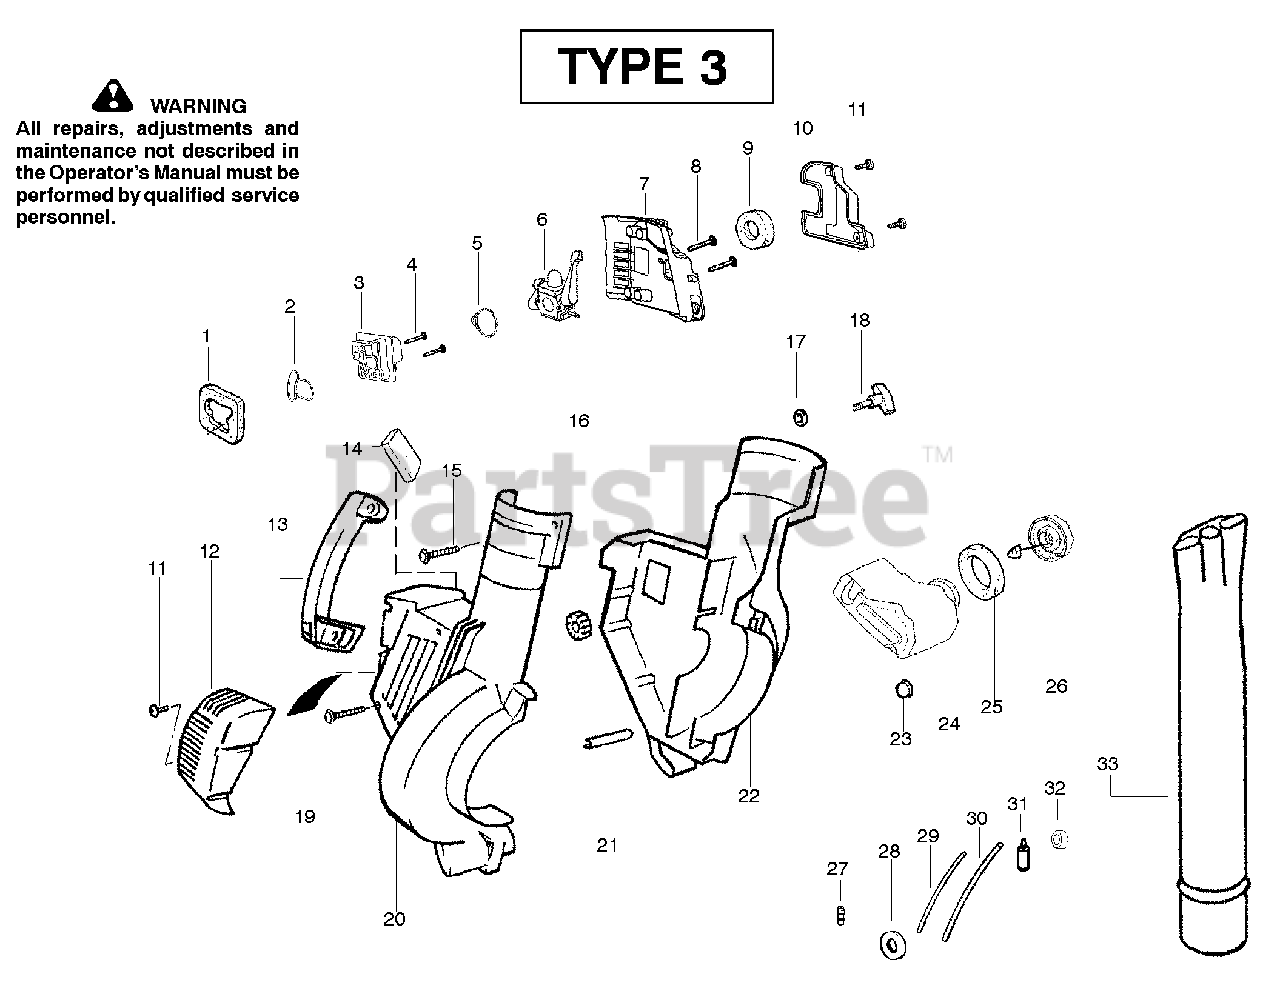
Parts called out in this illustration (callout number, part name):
1	Air Dam (kit)
2	Gasket-Adapter (kit)
3	Carburetor Adaptor
5	Gasket-Carburetor (kit)
6	Kit-Carb Ass'y. Zama-(C1Q-W11C)
6	Kit-Carb Ass'y. Walbro-(WT-606)
8	Screw-Carb.
9	Filter-Air
10	Cover-Air Filter
12	Guard-Muffler
14	Foam - 71.12mm (kit)
16	Isolator
18	Knob-Blower
19	Tape-Reflector (kit)
20	Shroud-RH
21	Guide-Starter Rope
22	Shroud-LH
23	Isolator-Crankcase
24	Assy-Fuel Tank
25	Gasket-Fuel Tank
26	Fuel Cap w/Retainer
27	Fitting-Fuel Line
28	Grommet-Shroud
29	Kit-Line Carb/Purge
30	Kit-Line Tank/Purge
31	Assy-Fuel Pick-up
32	Grommet-Fuel line (kit)
33	Tube-Blower
